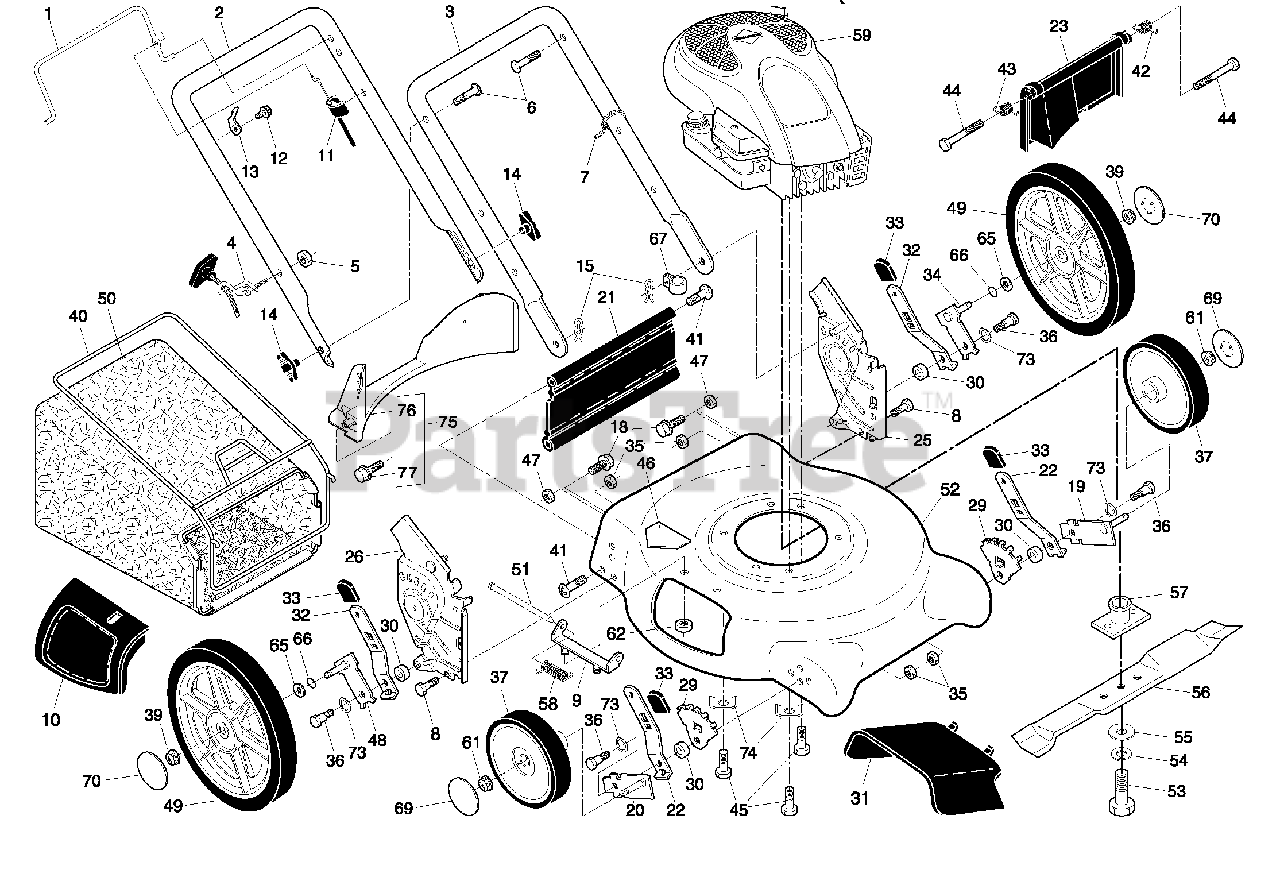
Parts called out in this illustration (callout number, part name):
1	Control Bar
2	Upper Handle
3	Lower Handle
4	Rope Guide
5	Locknut, Hex 1/4-20
6	Handle Bolt
7	Wire Tie
8	Hex Bolt 5/16-18 x 3/4
9	Mounting Bracket, Mulcher Door
10	Mulcher Door
11	Engine Zone Control Cable
12	Hex Washer Head Screw #10-24 x 1/2
13	Up-Stop Bracket
14	Handle Knob
15	Hairpin Cotter
18	Screw
19	Axle Arm Assembly, Front, LH
20	Axle Arm Assembly, Front, RH
21	Rear Skirt
22	Selector Spring, Front
23	Rear Door Assembly
24	Locknut, Hex 5/16-18
25	Handle Bracket, LH
26	Handle Bracket, RH
28	Wheel Adjusting Bracket
30	Spacer
31	Deflector, Discharge
32	Selector Spring, Rear
33	Selector Knob
34	Axle Arm Assembly, Rear, LH
35	Locknut, Hex 5/16-18
36	Shoulder Bolt 5/16-18
37	Wheel & Tire Assembly, Front, 8"
38	Shoulder Bolt
39	Flanged Locknut
40	Frame, Grassbag
41	Hinge Screw
42	Spring, Rear Door, LH
43	Spring, Rear Door, RH
44	Bolt, Rear Door
45	Screw, Hex Head Thread Rolling Screw 3/8-16 x 1
46	Danger Decal
47	Nut, Hex
48	Axle Arm Assembly, Rear, RH
49	Wheel & Tire Assembly, Rear, 12"
51	Rod, Hinge
52	Kit, Lawn Mower Housing
53	Hex Head Screw, Grade 8, 3/8-24 x 1-3/8
54	Helical Lockwasher
55	Hardened Washer
56	21" Blade
57	Blade Adapter
58	Spring, Hinge Rod
61	Flanged Locknut
62	Nut, Hex
65	Washer, Flat 3/8
66	O-Ring
67	Clip, Cable
69	Hubcap, Front Wheel
70	Hubcap, Rear Wheel
73	Washer, Curved, Cylindrical
74	Washer, Special, Engine
75	Kit, Rear Baffle
76	Baffle, Rear
77	Screw, Rear Baffle
77	Operator's Manual, English
77	Operator's Manual, French
77	Repair Parts Manual
